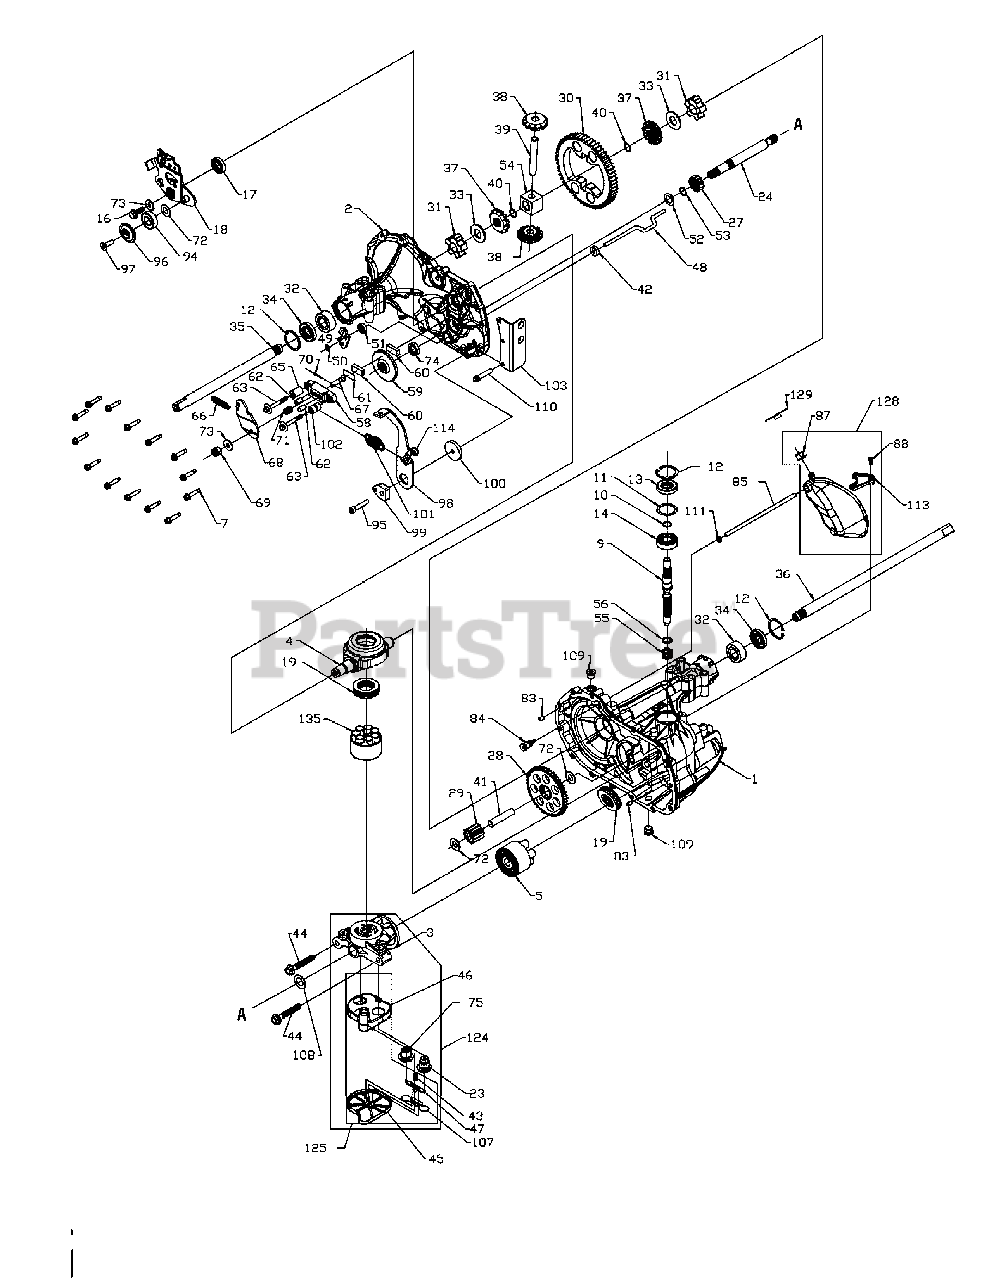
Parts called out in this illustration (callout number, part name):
1	Main Housing, Assembly
2	Side Housing, Assembly
3	Center Section, Assembly
4	Swashplate, Trunnion Machined
5	Block - Assembly
7	Hex Flange Screw 1/4-20 X 1.25
9	Shaft, Input
10	Ring, Retaining
12	Ring, Retaining
13	Seal, Lip .67 X 1.58 X .276
14	Ball, Bearing 17mm ID X 40mm OD X12mm
16	Bolt, Hex Flange Head 5/16-24 X .94 (Patch)
17	Lip Seal 18 X 32 X 7
18	Arm, Control
19	Bearing, 30 X 52 X 13 Thrust
23	Shock Valve Assembly
24	Shaft, Motor
27	Gear - Pinion, 12T
28	10T/49T Gear
29	Gear, LDT Jackshaft
30	60T Bull Gear
31	Sleeve Bearing .75 X 1.750 X .625
32	Sleeve Bearing (Outboard) .75 X 1.575 X .625
33	Washer, 3/4 X 1 1/2 X .13 THK
34	Lip Seal Axle Seal
35	Shaft, Axle (R.H.)
36	Shaft, Axle (L.H.)
37	Miter Gear 12T (Splined)
38	Miter Gear 12T
40	Ring, Spiral Retaining
41	Pin, Jackshaft
42	Magnet, Ring
43	Spring, Bypass
44	Bolt, Hex Flange 3/8-24 X 2.5
47	Actuator, Bypass
48	Rod, Bypass Actuator
49	Arm, Bypass
50	Retaining Ring, 250 External
51	Seal, Lip .741 X .250 X 250 TC
52	Flat Washer
53	Retaining Ring
54	Bearing, Center Block
55	Spring - Helical Compression
58	Brake, Yoke
59	Rotor, Brake
60	Brake, Puck
61	Puck Plate
62	Brake Actuating Pin
63	HFHCS 1/4-20 X 2 w/Patch SPECIAL FLANGE
66	Spring, Brake ARM BIAS
67	Sq. HD, Bolt 5/16-24
68	Arm, Brake
69	Slotted Hex Nut, 5/16-24
70	Cotter Pin, 3/32 X 3/4
71	Compression Spring Anti-Drag
73	Flat, Washer 11/32 I.D. X 7/9 O.D
74	Seal, Kit
75	Check Plug Assembly, .027 Washer
83	Pin, Standard Headless
84	Fitting, 5/16 SAE 5/32 Tube
85	Hose, Expansion Tank
87	Cap, Vent
88	Bolt, Self Tapping 10-32 x 1/2
93	Spring, Clip - Housing Thrust
94	Bearing, Ball .62 ID X 1.39 .44
95	Screw, Socket Head Cap 5/16-24 X 1 1/2
96	Spacer, Locating
97	Screw, SFHCS 5/16-18 X 1
98	Arm, Return
99	Puck, Adjusting
100	Washer
101	Spring, Extension
102	Spacer, .260 ID X .560 OD X .870
103	Bracket, Torque
107	Deflector
108	Washer, Motor Shaft .71 ID X 1.15 OD X .030 THK
110	Screw, Torx Head 5/16-18 T.F.
111	O-Ring .103 X .299 ID
113	Bracket, Support Expansion Tank
114	Spring, Guide
124	Center Section - Filter - Bypass Assembly
125	Filter Assembly
128	Kit, Expansion Tank
135	Block - Assembly
